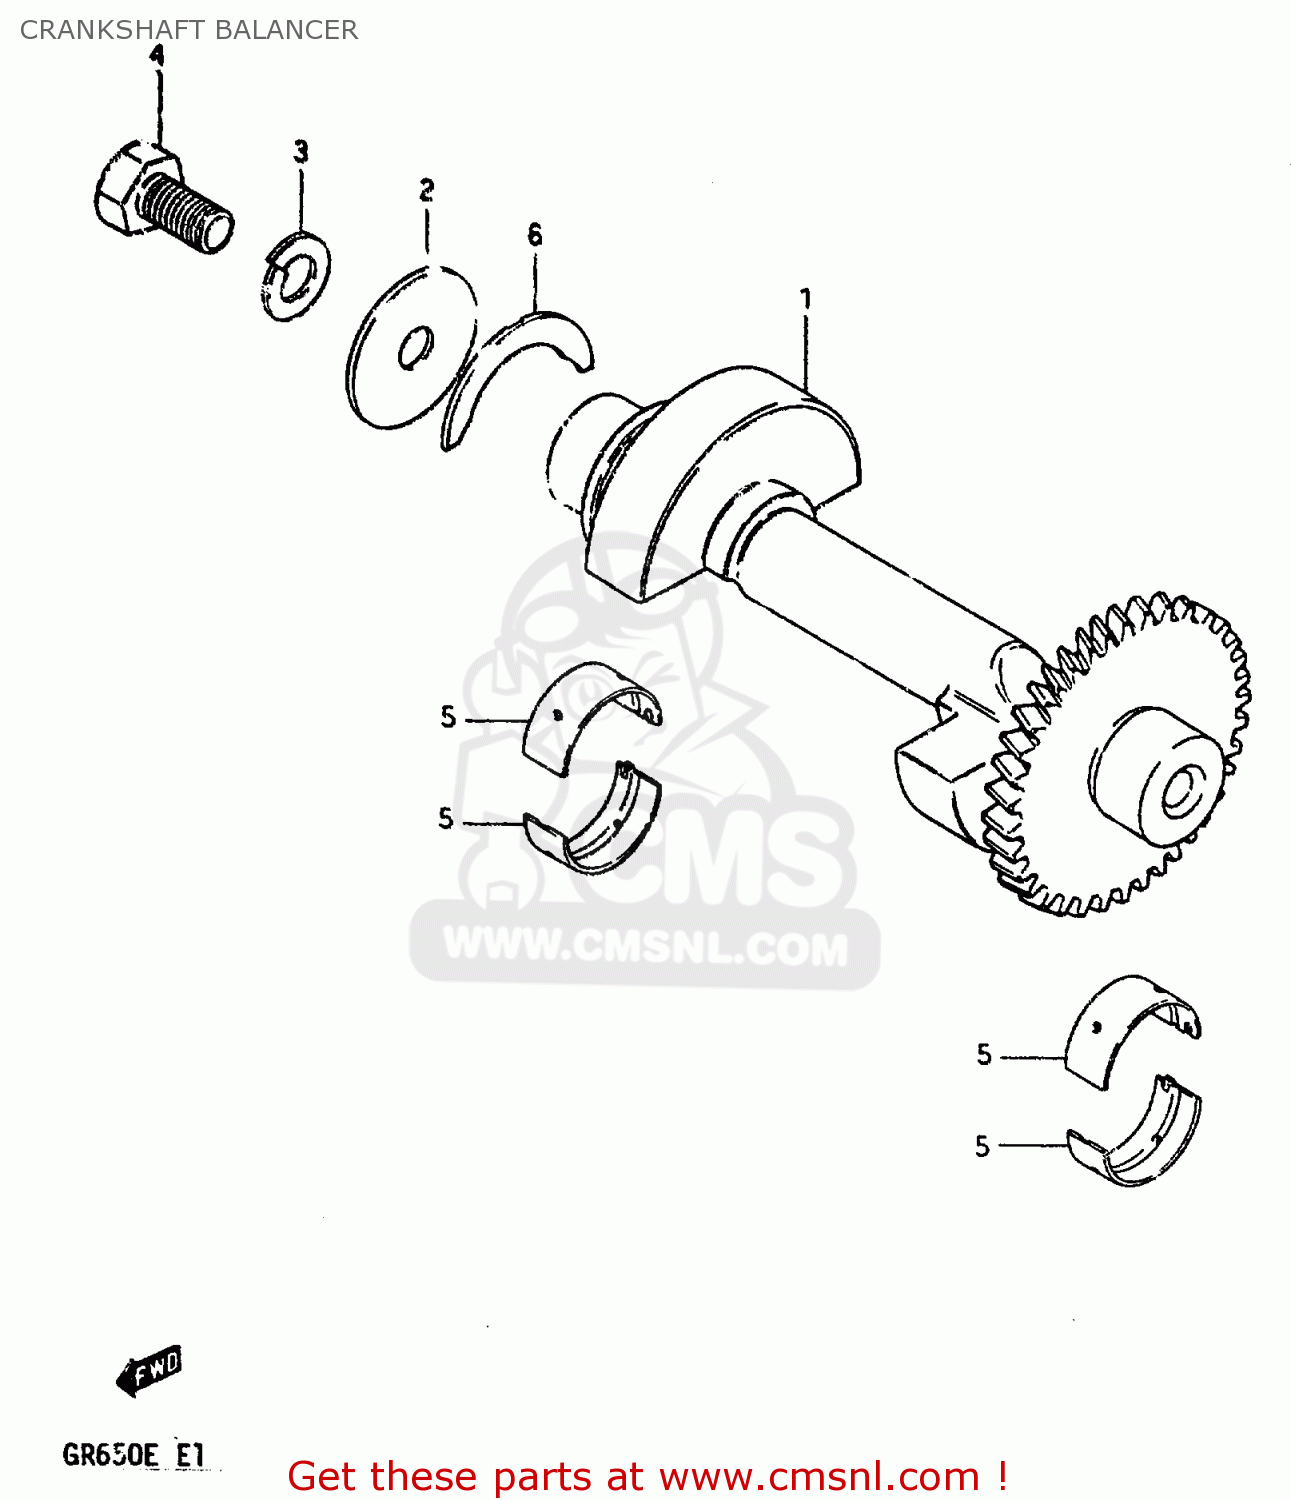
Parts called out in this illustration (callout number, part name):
1	BALANCER,CRANKSHAFT
2	WASHER,CRANK THRUST
3	WASHER,LOCK 12
4	BOLT
5	METAL CRANKSHAFT (BROWN)
6	PLATE,CRANK THRUST
